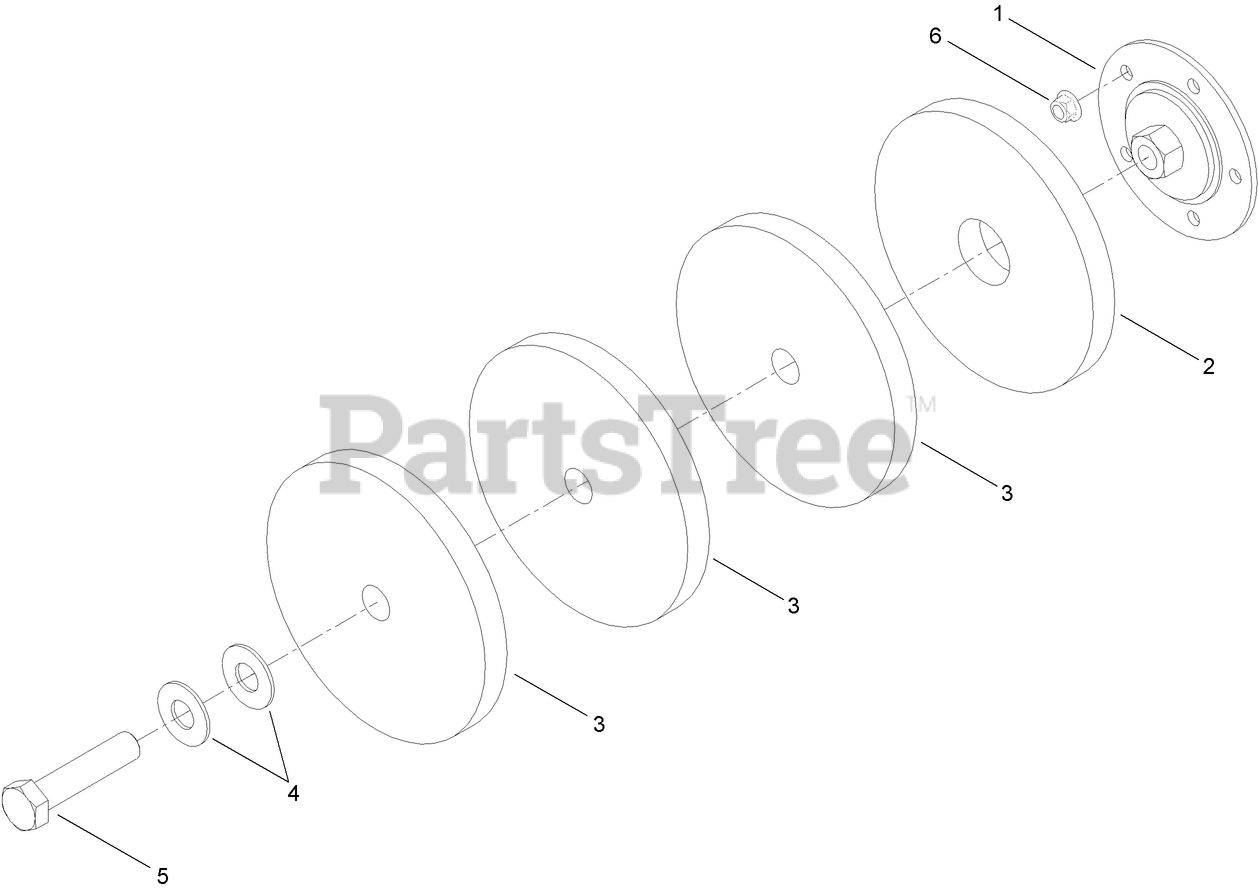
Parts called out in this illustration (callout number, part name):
1	PLATE-RETAINER
2	PLATE-INNER WHEEL WEIGHT
3	PLATE-WHEEL WEIGHT
4	Washer-Flat
6	NUT-HHF
